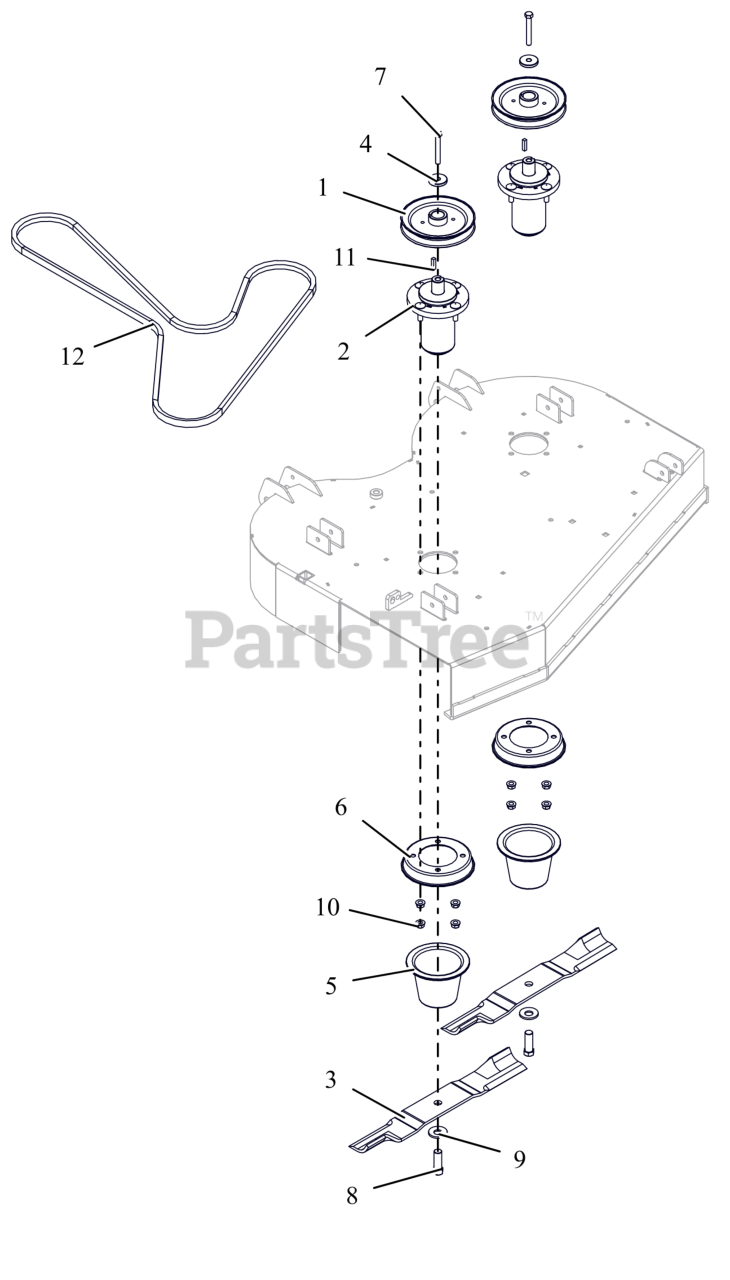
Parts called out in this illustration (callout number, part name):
1	PULLEY, V-1" ID X 6.00 OD
2	ASM, MAINT FREE ALUM SPINDLE
3	BLADE, 18.00" MOWER (HI-LIFT)
4	RETAINER, SHEAVE
5	GUARD, SPINDLE LOWER
6	GUARD, SPINDLE TOP
7	BLT, HEX .38-16X2.75 G8 ZCC
8	BLT, HEX .62-18X1.75 G8 ZCC
9	WSHR-BLVL .669X1.535X.138
10	NUT-LK-CTR-FLG .375-16 GF ZCC
11	KEY, SQ .25X.25X1.00 RC 40-50
12	V-BELT, B RAW EDGE EPDM
